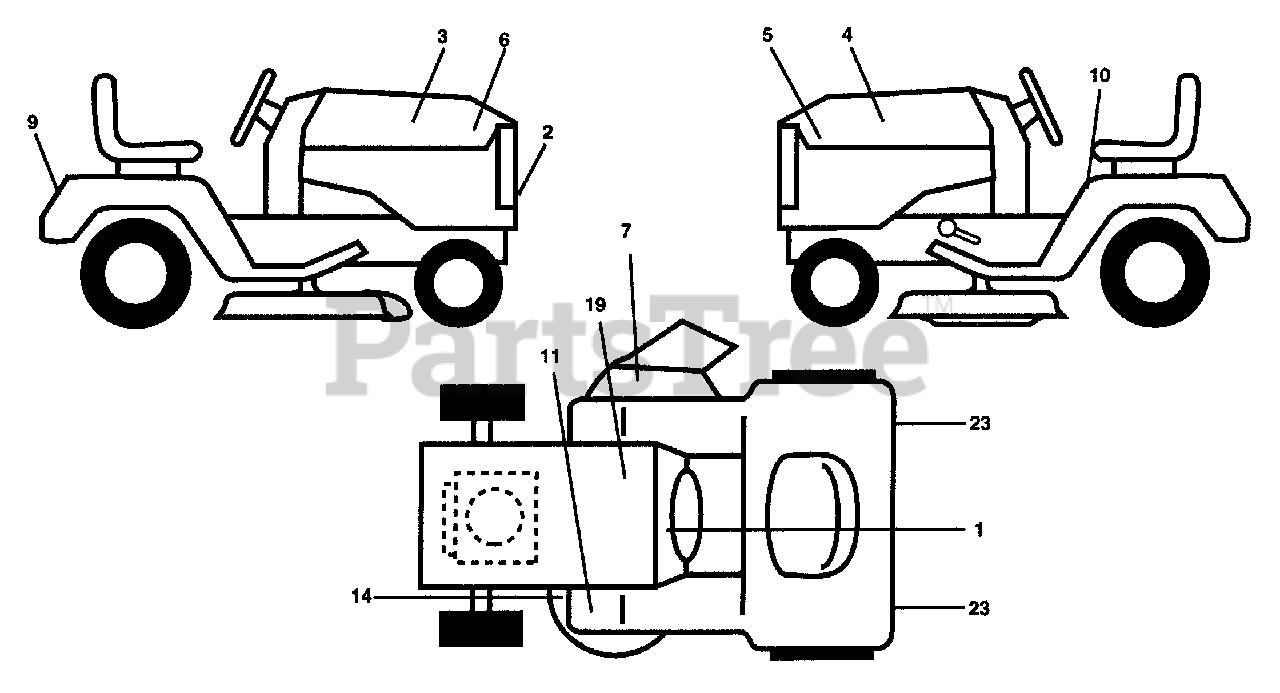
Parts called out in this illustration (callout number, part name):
1	Decal, Operating Instruction
2	Decal, Grille Husqvarna "H" Logo
3	Decal, Hood, RH
4	Decal, Hood, LH
5	Decal, Insert Hood LH GT200 6Sp
6	Decal, Insert Hood RH GT200 6Sp
7	Decal, Warning Multi-Language
9	Decal, Fender
10	Decal, Caution
11	Decal, Clutch/Brake
14	Decal, V-Belt Schematic
19	Decal, Battery
23	Reflector, Taillight
